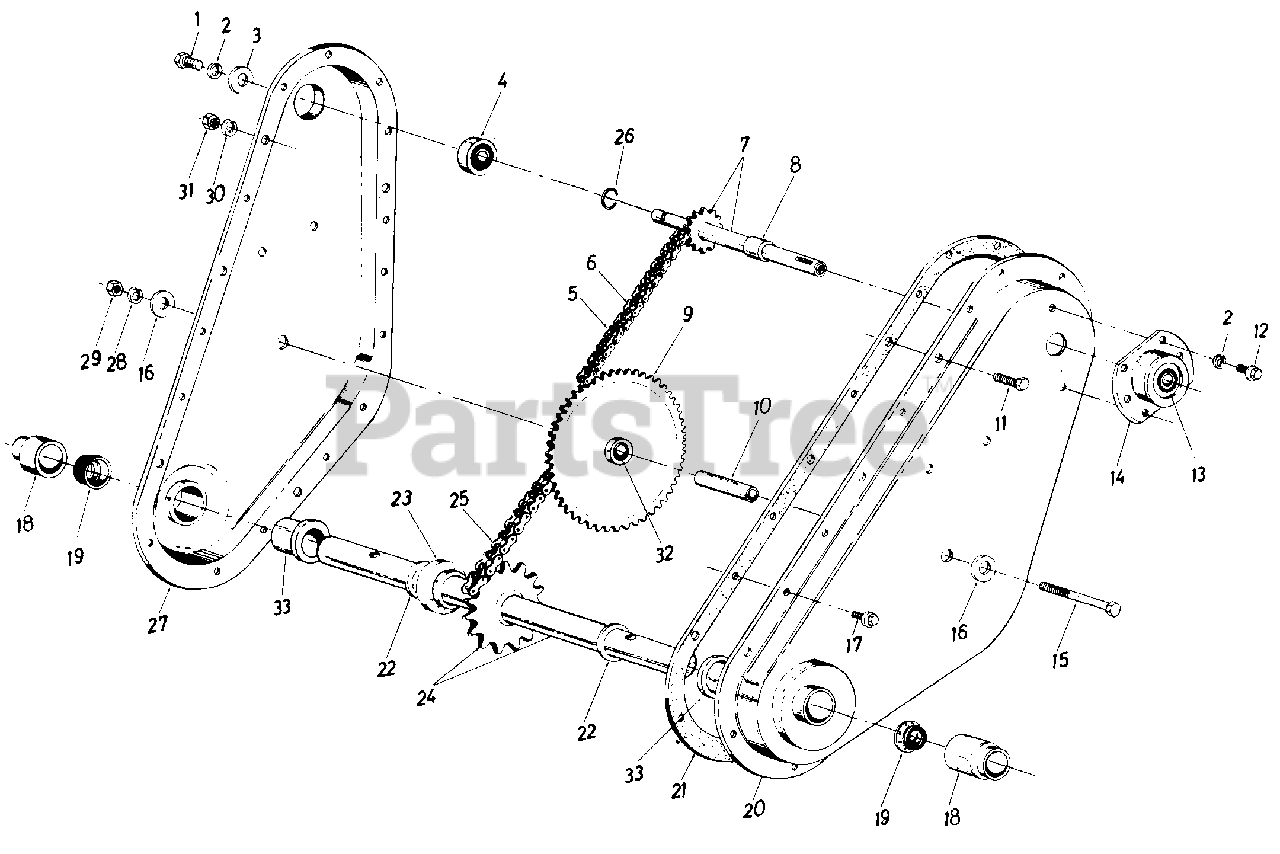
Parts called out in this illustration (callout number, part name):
1	Hex L-Scr. 1/4-28 x .625" Lg.
2	L-Wash. 1/4" I.D.
3	Fl-Wash. .25" I.D. x .93" O.D. x .125" Thk.
4	Bearing .62" I.D. x 1.38" O.D. x .437" Thk.
5	#35 Chain 3/8" Pitch x 52 Links-Endless
6	Master Link
7	Input Shaft Assembly
8	Spacer
9	Sprocket Assembly
10	Sprocket Hub Tubing 3/8" I.D. x 5/8" O.D. x 1.9" Lg.
11	Hex Scr. 5/16-18 x .625" Lg.
12	Hex Wash. Hd. Self-Tap Scr. 1/4-20 x .50" Lg.
13	Bearing .625" I.D. x 1.38" O.D. x .437" Thk.
14	Bearing Housing
15	Hex Scr. 3/8-24 x 2.75 Lg.
16	Fl-Wash. 3/8" I.D. x 1.25" O.D. x .100 Thk.
17	Hex Wash. Hd. Self-Tap Scr. 1/4-20 x .50" Lg.
18	Dust Cap
22	Thrust Wash. 1.00" I.D. x .030" Thk.
23	Step Spacer
24	Tine Shaft Assembly
25	#50 Chain 518" Pitch x 46 Links-Endless
26	Snap Ring
29	Hex Nut 3/8-24 Thd.
30	L-Wash. 5/16" Scr.
31	Hex Nut 5/16-18 Thd.
32	Bearing
33	Bearing
